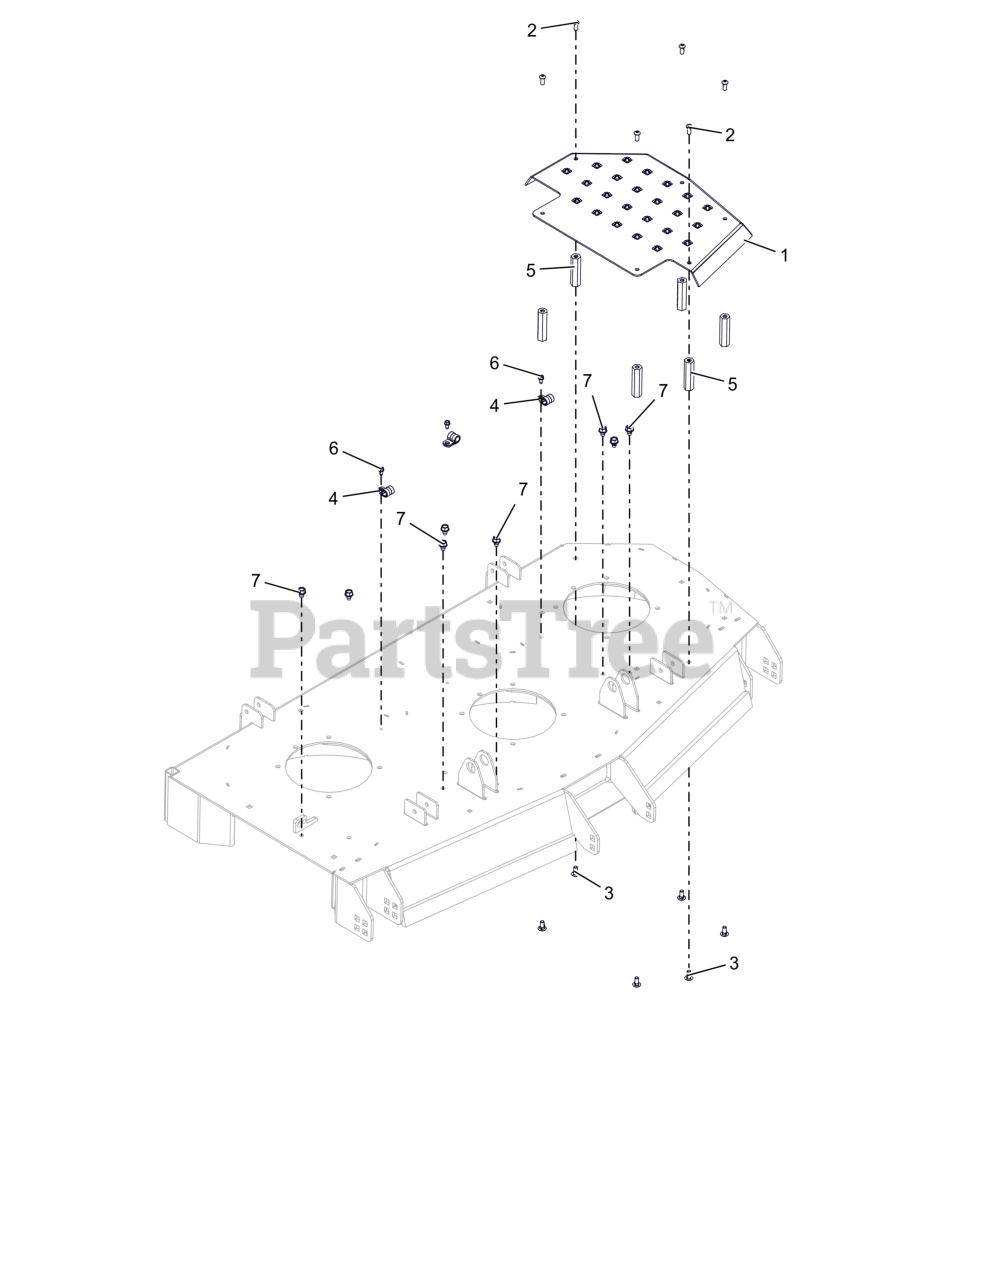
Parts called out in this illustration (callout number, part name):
1	PLATFORM, WLDMT 52 SD DECK STEP (RED)
2	SCR-SKH .31-18X.75 BTNHD YWZC
3	BTL,RHSN .313-18 X 0.75 G5 ZCC LT
4	CLAMP, CUSHIONED STEEL
5	NUT, COUPLING .31-18 X 3.00
6	SCR-TAP .25-20X.50 HWH ZCC
7	SCR,TAP .375-16X.50 HWH TR ZCC
